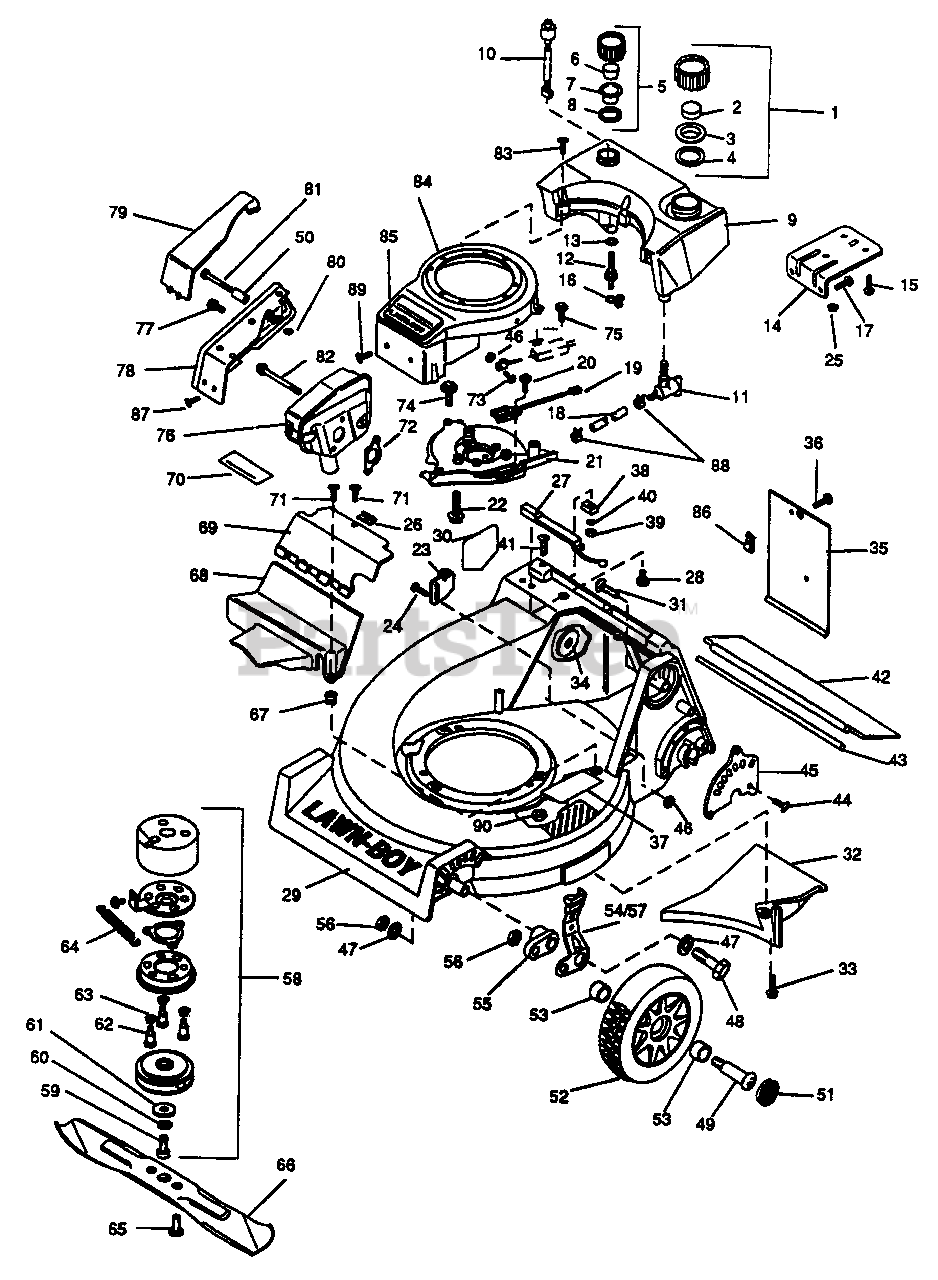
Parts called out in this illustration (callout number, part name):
1	Fuel Cap Assembly (Inc. 2-4)
2	Baffle
3	Baffle Cover
4	Gasket
5	Oil Cap Assembly (Inc. 6-8)
6	Baffle
7	Baffle Cover
8	Gasket
9	Fuel/Oil Tank (Inc. 10-13)
10	Switch-Low Oil
11	Fuel Shut-Off Valve
12	Oil Fitting Assy (Inc. 13)
13	O-Ring
14	Fuel Tank Bracket
15	Screw
16	Clamp-Oil Hose
17	Screw-Tank Bracket to Block
18	Fuel Line
19	Brake Interlock Switch
20	Screw-Interlock Switch to Plate
21	Engine Mounting Plate
22	Screw-Mounting Plate to Engine
23	Cable Anchor
24	Screw-Anchor to Housing
25	Nut-Hex Flange
26	Speednut
27	Switch Assy-Bag Lock
28	Screw
29	Housing Assy (Inc. 30-34)
30	Decal-Blade Contact Warning
31	Handle Mounting Bolt
32	Baffle
33	Screw
34	Washer-R.H. Handle Mounting
35	Access Door
36	Screw
37	Decal-Foot Pad
38	Magnet Assembly
39	Nut
40	Lockwasher
41	Screw
42	Trailing Shield
43	Rod-Trailing Shield
44	Screw
45	Height Adjust Plate
46	Nut
47	Washer
48	Screw
49	Bolt-Wheel
50	Spacer-Muffler Guard
51	Cap-Hub
52	Wheel & Tire Assy (Inc. 53)
53	Bushing-Wheel
54	Knob & Spring Assy-L.H.
55	Front Height Adj Arm
56	Nut
58	Clutch & Brake Assy (Inc. 59-64)
59	Screw
60	Lockwasher
61	Washer
62	Screw
63	Spring-Compression
64	Spring-Extension
65	Screw-Blade
66	21" Blade
67	Grommet
68	Lower Drive Cover
69	Upper Drive Cover w/Decal (Inc. 70)
70	Decal-Warning
71	Screw
72	Exhaust Gasket
73	Bolt
74	Screw-Mtg Plate To Housing
75	Screw
76	Muffler
77	Screw-Muffler Guard
78	Muffler Guard Assy (Inc. 79-80)
79	Muffler Cover
80	Pushnut
81	Screw-Muffler Guard
82	Screw-Muffler
83	Screw-Fuel Tank
84	Shroud & Applique Assy (Inc. 85)
85	Applique
86	Speednut
87	Screw-Muffler Guard
88	Clamp-Fuel Line
89	Screw-Shroud
90	Locknut-Mounting Plate to Housing
